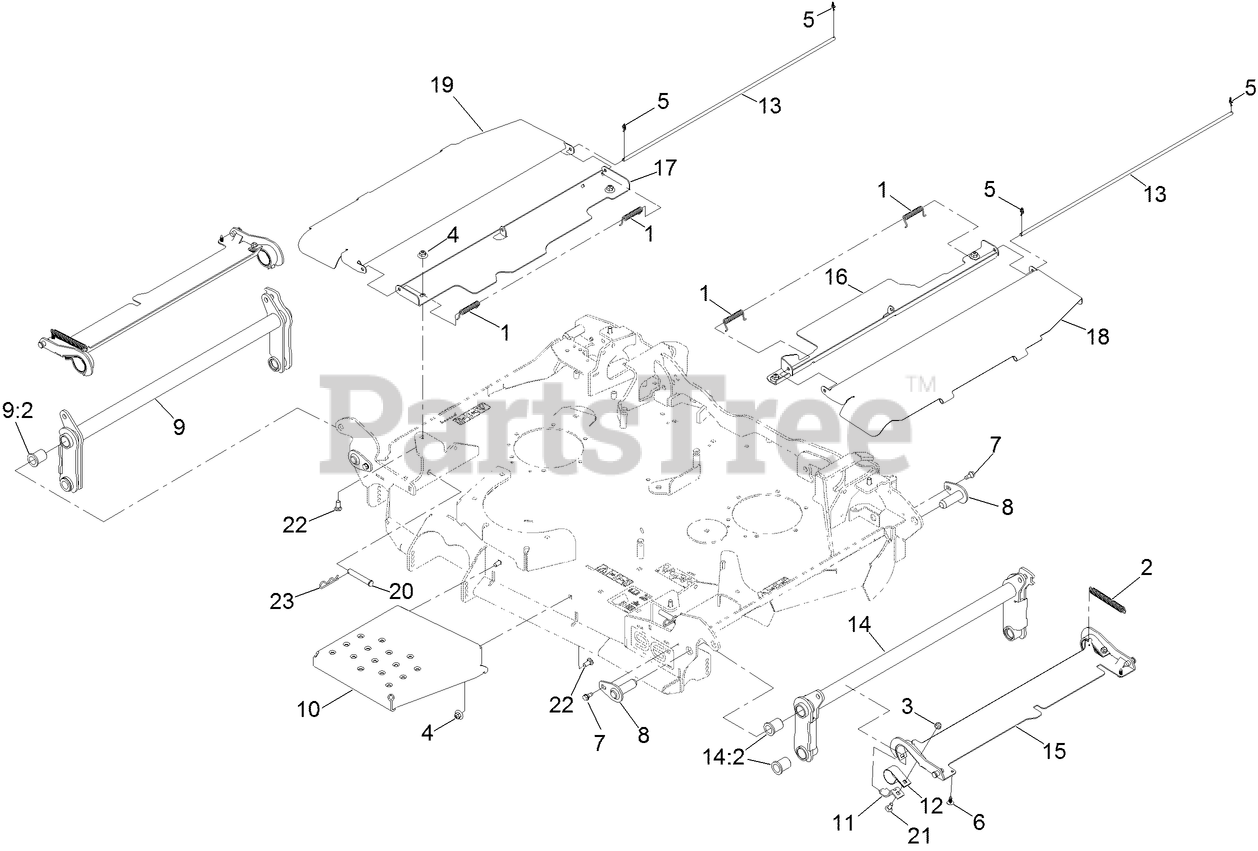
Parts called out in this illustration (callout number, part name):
1	SPRING-TORSION
2	SPRING
3	NUT-HF, NI
4	NUT-FLANGE, NI
5	PIN-COTTER, LOCKING
6	PLUG-PLASTIC
7	SCREW-SHOULDER
8	ASM-DECK PIN
9	ASM-FOLS ARM, RH
9:2	BUSHING-FLANGED
10	PANEL-STEP
11	PLATE-RETAINER, BEARING
12	BEARING-STRAP, NYLON
13	COVER-ROD, PIVOT
14	ASM-FOLD ARM, LH
14:2	BUSHING-FLANGED
15	COVER-WING
16	SHIELD-CENTER, LH
17	SHIELD-CENTER, RH
18	PANEL-SHIELD HINGE, LH
19	PANEL-SHIELD HINGE, RH
20	PIN-CLEVIS
21	SCREW-CARR
22	BOLT-CARR
23	PIN-HAIR
